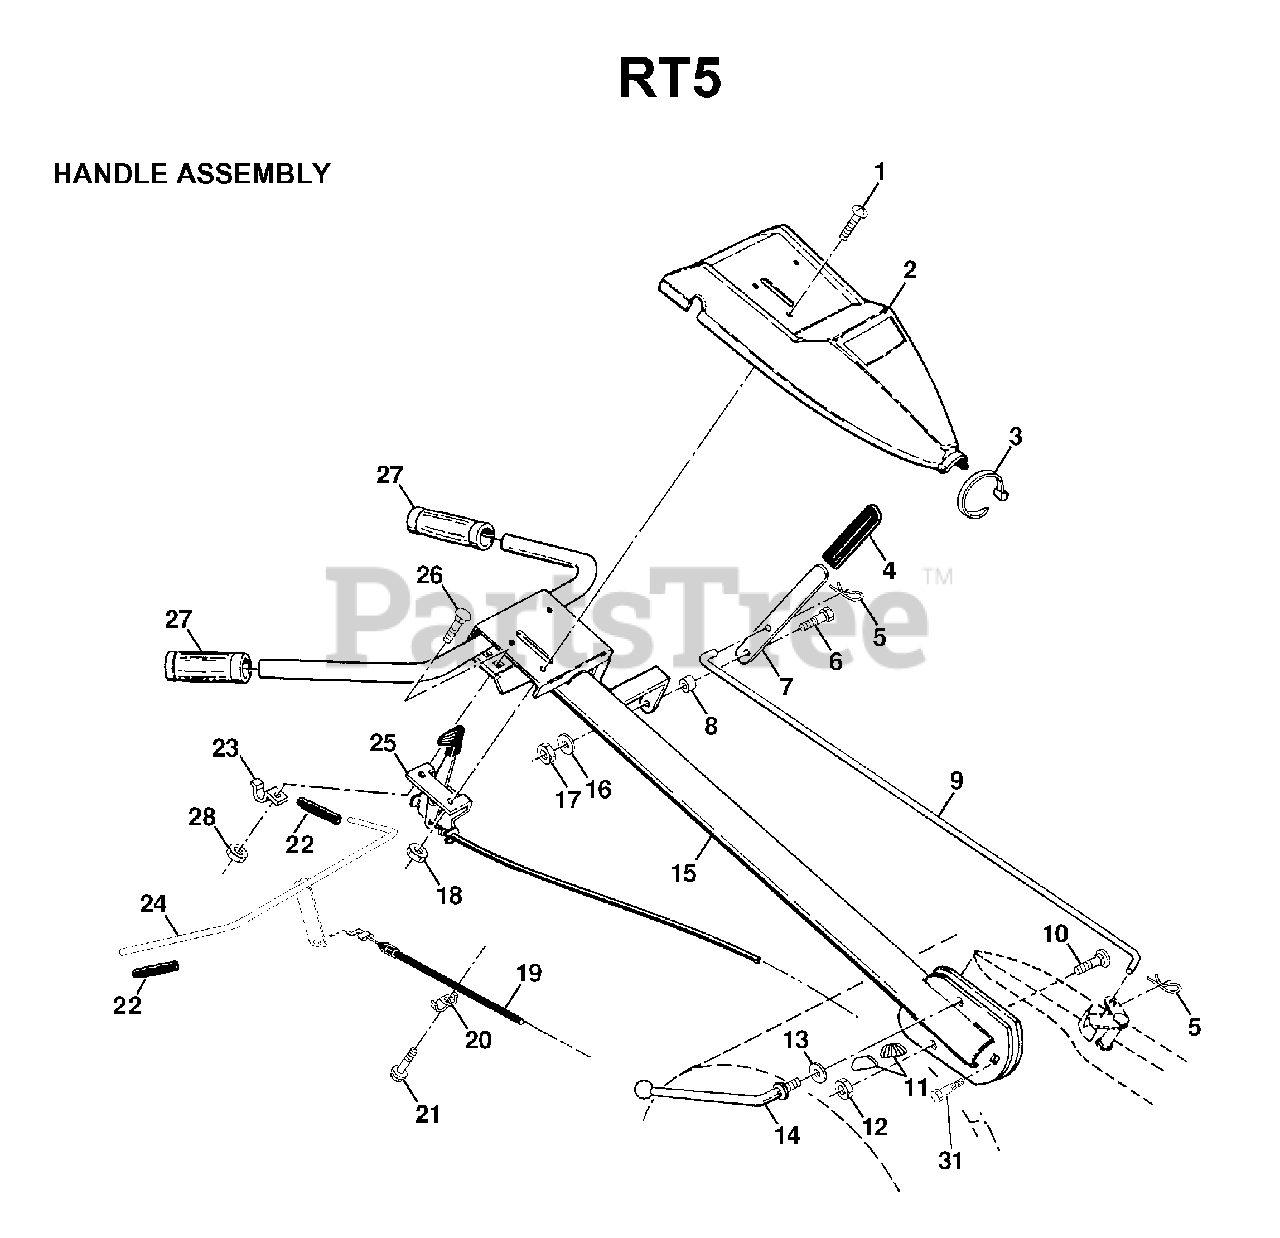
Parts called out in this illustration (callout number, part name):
1	SCREW.PNHD.10-24
3	TIE CABLE CRT
4	GRIP T
5	RETAINER M
6	SHOULDER BOLT ST
7	SHIFT HANDLE CRT
8	GROMMET.RUBBER.CRT.TILLER
9	SHIFT ROD CRT
12	LOCKNUT
13	WASHER CRT
14	LEVER.LOCK.CRT
16	LOCKWASHER
17	NUT
18	NUT **
19	CABLE.CLUTCH
20	CONDUIT CLIP T
21	TAPPING SCREW
22	GRIP BAR CRT(1)
23	CLAMP.BAR.CRT.BLACK
24	CONTROL BAR ASSY
25	CONT,THROTTLE
27	GRIPS (2EACH)
28	NUT
31	BOLT.PIVOT
